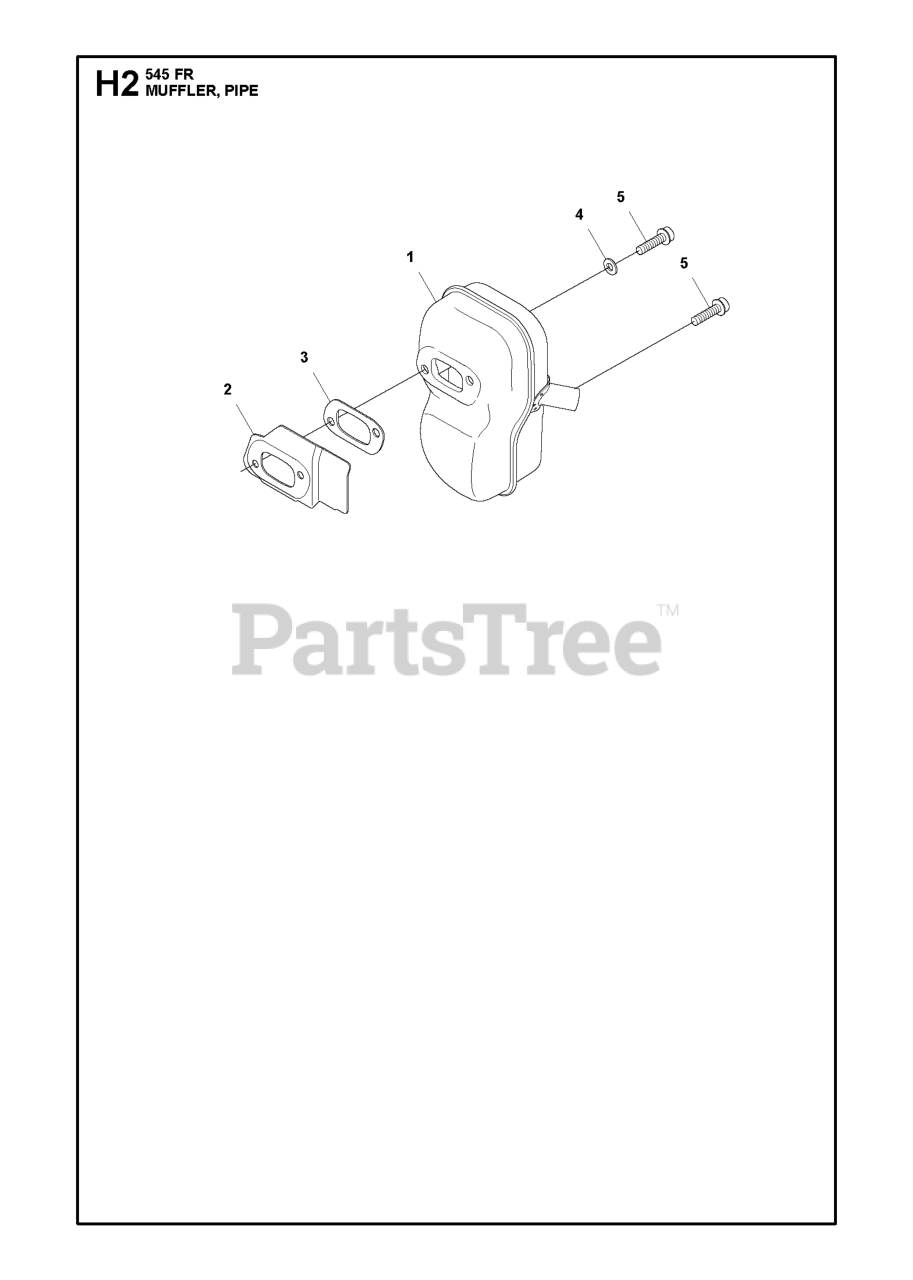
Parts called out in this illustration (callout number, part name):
1	MUFFLER KIT NEW BAFFLE
2	HEAT DEFLECTOR
4	DOUBLE WASHER
